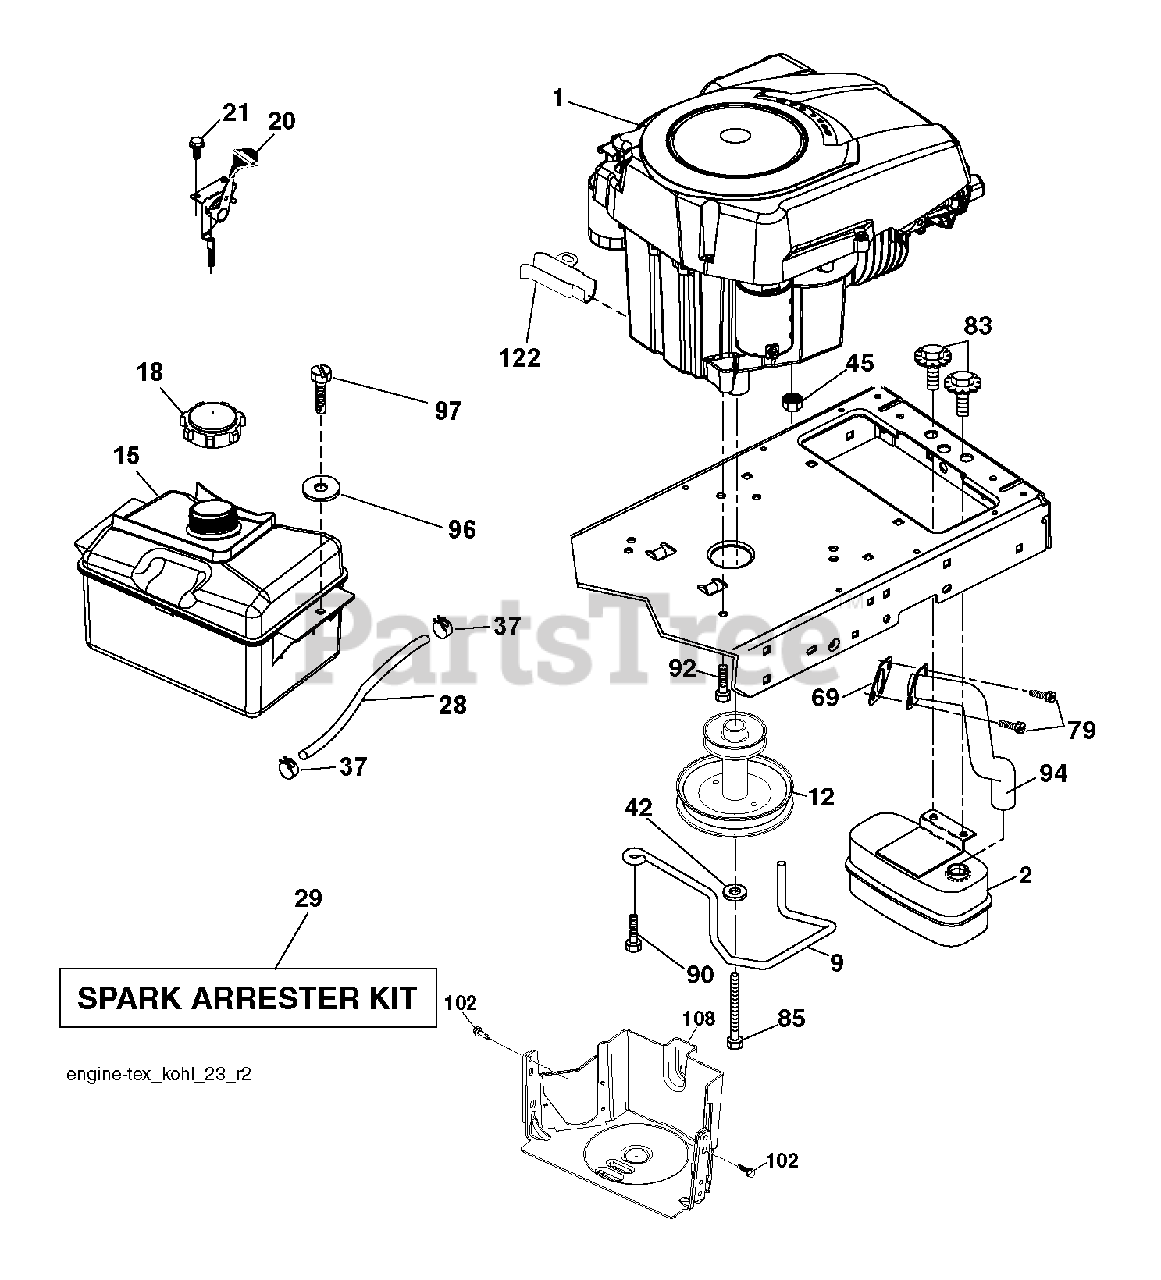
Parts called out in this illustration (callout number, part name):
2	MUFFLER.SINGLE.CYL.KOHL/B&S
9	KEEPER.BELT.ENGINE.4.2
12	PULLY ENGINE
15	RP TANK FUEL FRT 1.5 GAL
18	CAP ASM.FUEL.2.25"FR.
20	CONTROL.TH/CK.C.
21	SCREW.#10 X 0.750.BOS
28	LINE.FUEL.20
29	KIT.SPARK ARRESTOR 794945 B&S
37	HOSE CLAMP
42	LOCKWASHER
45	NUT
69	GASKET.EXHAUST.KOHLER
79	SCREW.SOCKET HD.5/16-1
83	BOLT, 5/16-18 X 1 3/4
85	BOLT HEX 7/16-20X4-1/4"
90	SCREW 3/8-16X1
92	SCREW 3/8-16X1
94	RP.TUBE.EXHAUST.KOHL.COURAGE
97	SCREW HEXWSHR 1/4-20X3/4
102	SCREW 5/16-18X1
108	COVER PULLEY
122	EXTENSION DRAIN OIL
